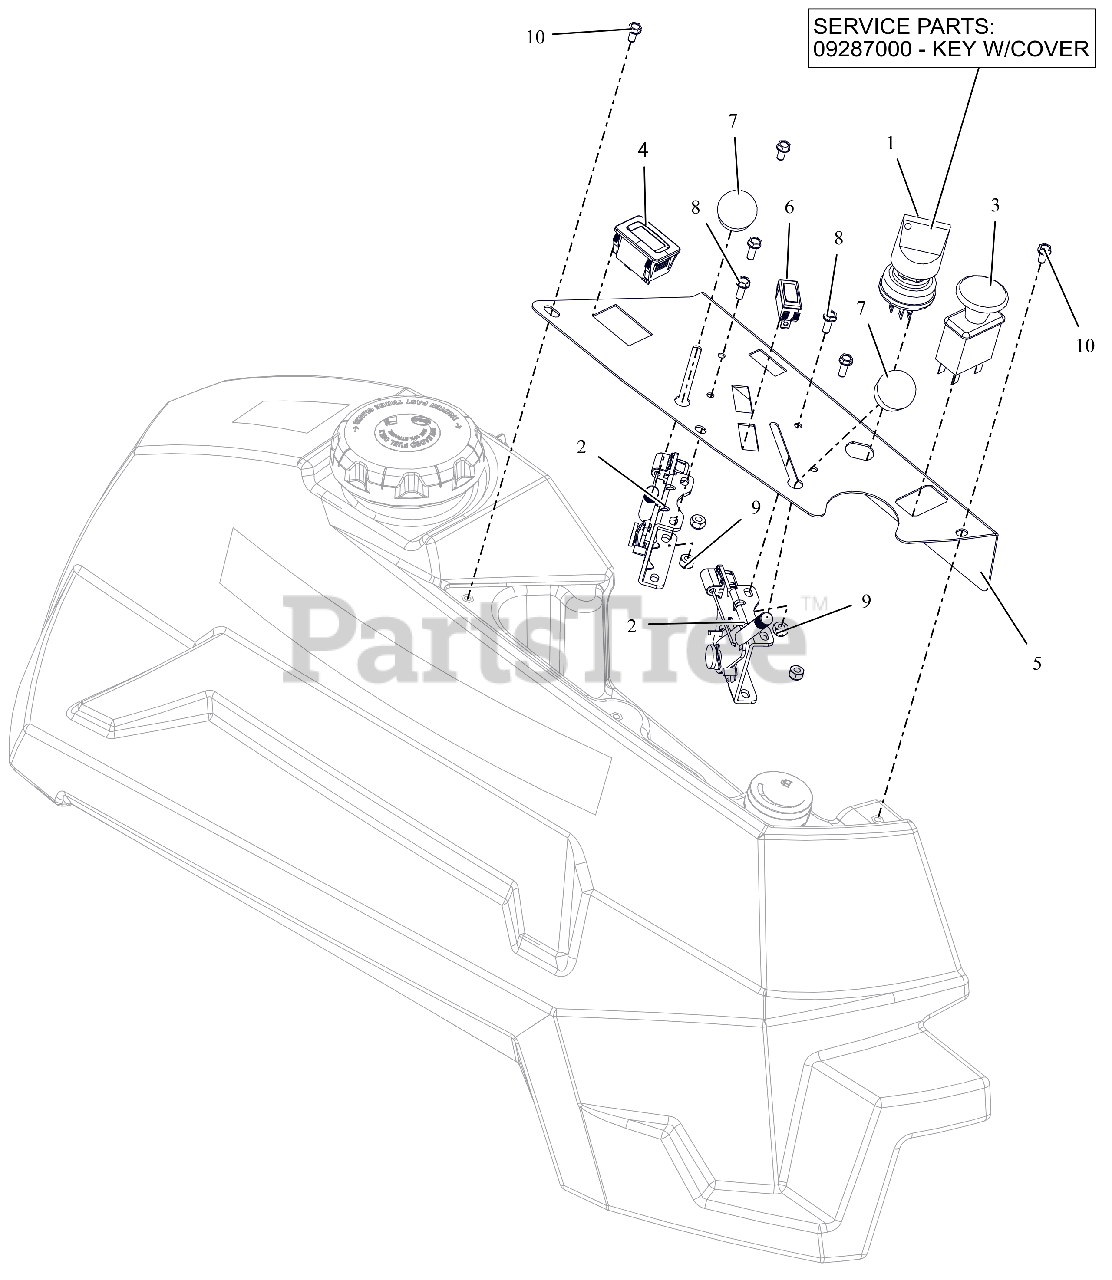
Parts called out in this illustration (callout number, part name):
1	SWITCH, IGNITION
1	KEY, W/ SHIELD
2	CABLE, PRO-CTRL 35.50"
3	SWITCH, CLUTCH
4	HOUR METER
5	PT400 CONTROL PANEL - RED
6	LIGHT, INDICATOR (RED)
7	KNOB-CONTROL-BLACK .38-16X.50
8	BLT, HWH #10-24X.50 ZCC
9	NUT-LK-NYL #10-24 G2 ZCC
10	SCR-MCH 10-24X.38 HWHSTAINLESS
